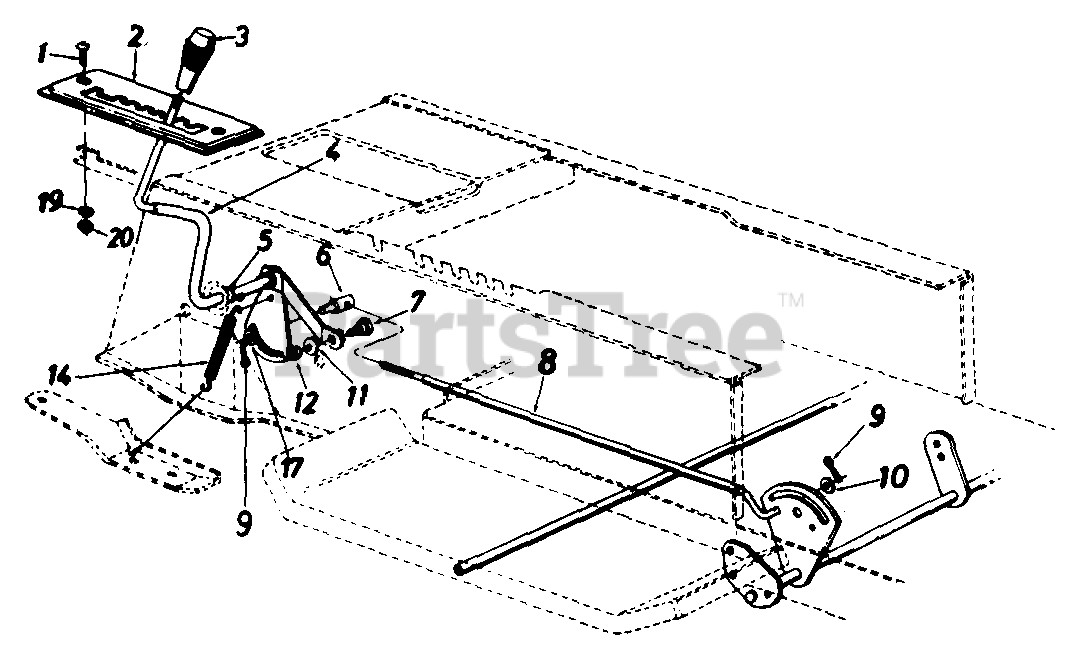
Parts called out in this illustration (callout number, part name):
1	Truss Mach. Scr. 1/4-20 x .75" Lg.
2	5-Speed Selector Plate
4	Speed Selector Lever Ass'y.
5	Flat Washer .53" I.D. x .93"
6	Ferrule 3/8-24 x .37" Dia.
7	Shoulder Bolt
8	Speed Control Link
9	Cotter Pin 3/32" Dia. x 1.0"
10	Fl-Wash..469" I.D. x.88"
11	L-Wash. 5/16" I.D.
12	Hex Nut 5/16-18 Thd.
14	Spring .38" O.D. x 3.18" Lg.
17	Fl-Wash, .385" I.D. x .62"
19	L-Wash. 1/4" I.D.
20	Hex Nut 1/4-20 Thd.
